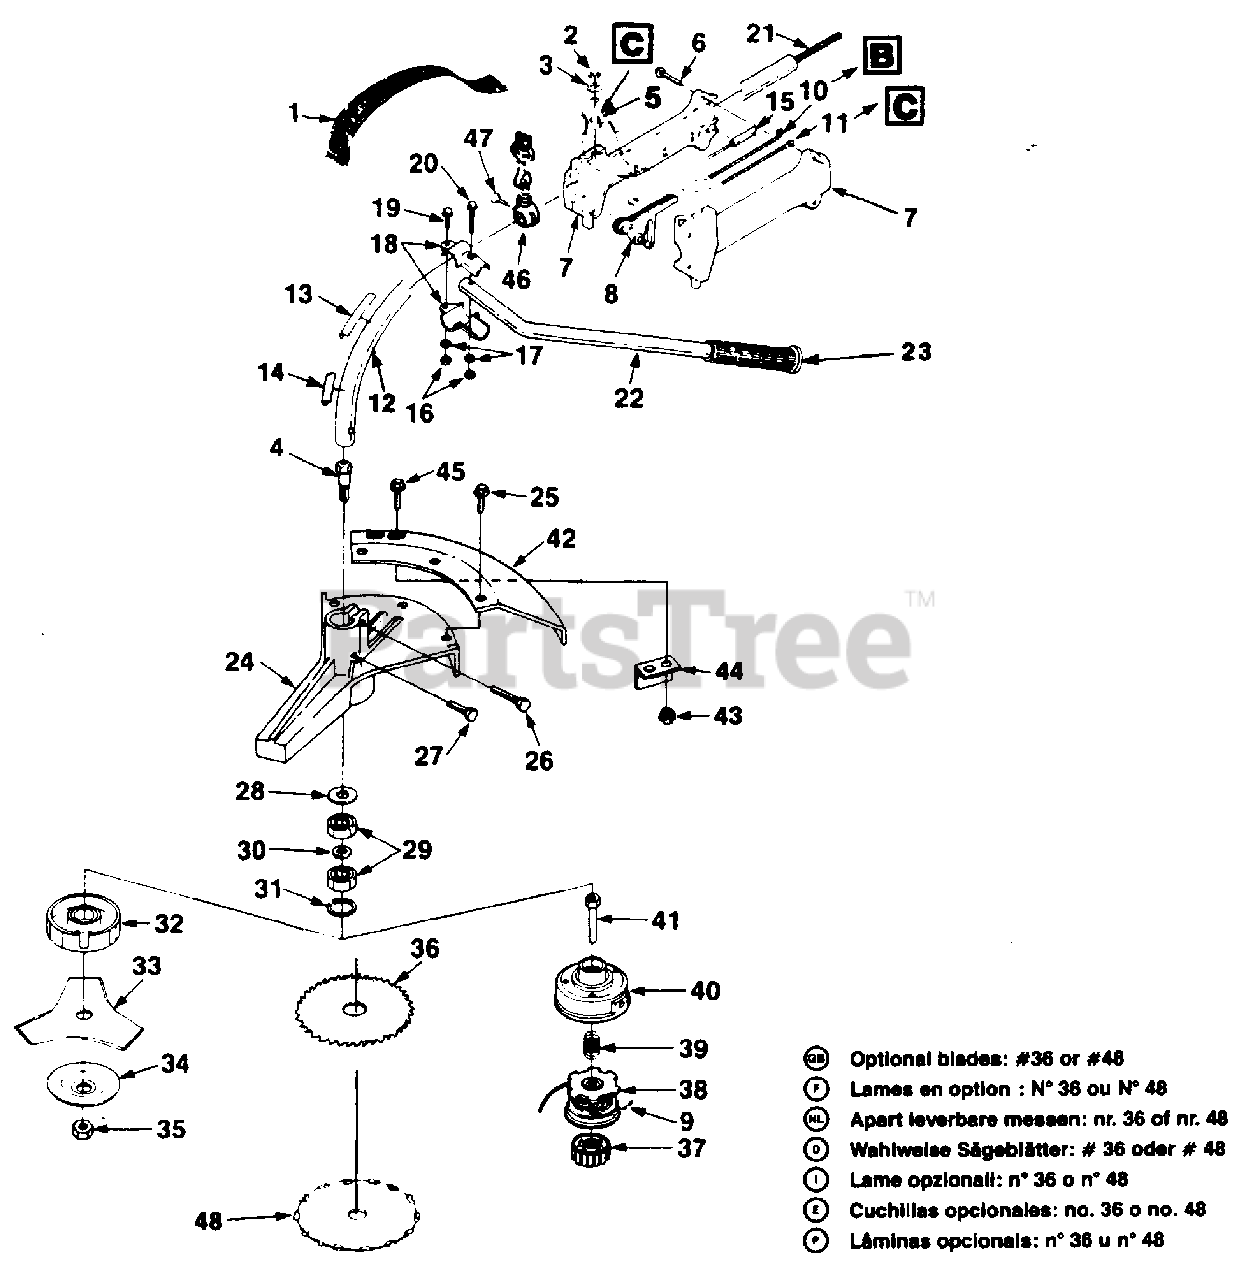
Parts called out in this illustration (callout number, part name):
1	HARNESS w/CONNECTOR
2	NUT
3	PLATE- Indicating
4	SHAFT- Spindle
5	SWITCH- Toggle
6	SCREW- Plastite (#8 x 3/4")
7	HANDLE GRIP ASSEMBLY
8	TRIGGER
9	LINE- Replacement (.080 Dia.) (100 Ft.)
10	LEAD- Electrical
11	LEAD- Ground
12	HOUSING- Driveshaft
13	DECAL- Starting Instructions
14	DECAL- Warning
15	CABLE- Throttle
16	NUT (1/4-20)
17	WASHER (1/4")
18	CLAMP- Handle bar
19	SCREW (1/4-20 x 1")
20	SCREW (1/4-20 x 1 1/2")
21	SHAFT- Flexible
22	HANDLE BAR
24	HOUSING- Lower bearing
25	SCREW (1/4-20 x 1/2")
26	SCREW (1/4-20 x 1")
27	SCREW (10-24 x 1/2")
28	WASHER- Thrust
29	BEARING- Ball
30	SPACER- Bearing
31	RING- Retaining
32	WASHER- Flange
33	BLADE- Tri-Arc (8")
34	WASHER- Cupped
35	NUT- Hex locking (R.H.)
36	BLADE- Saw (8") (optional)
37	RETAINER- Spool (R.H. Thread)
38	SPOOL & STRING (Dual Line)
39	SPRING- Compression
40	HOUSING & EYELET (Dual Line)
41	CONNECTOR- Drive
42	DEFLECTOR- Grass
43	NUT (10-32)
44	BLADE- Cut-off
45	SCREW (10-32 x 3/8")
46	BRACKET- Hanger
47	SCREW- Thumb (10-24 x 1/2")
48	BLADE- Saw 7" "Machete" (optional)
